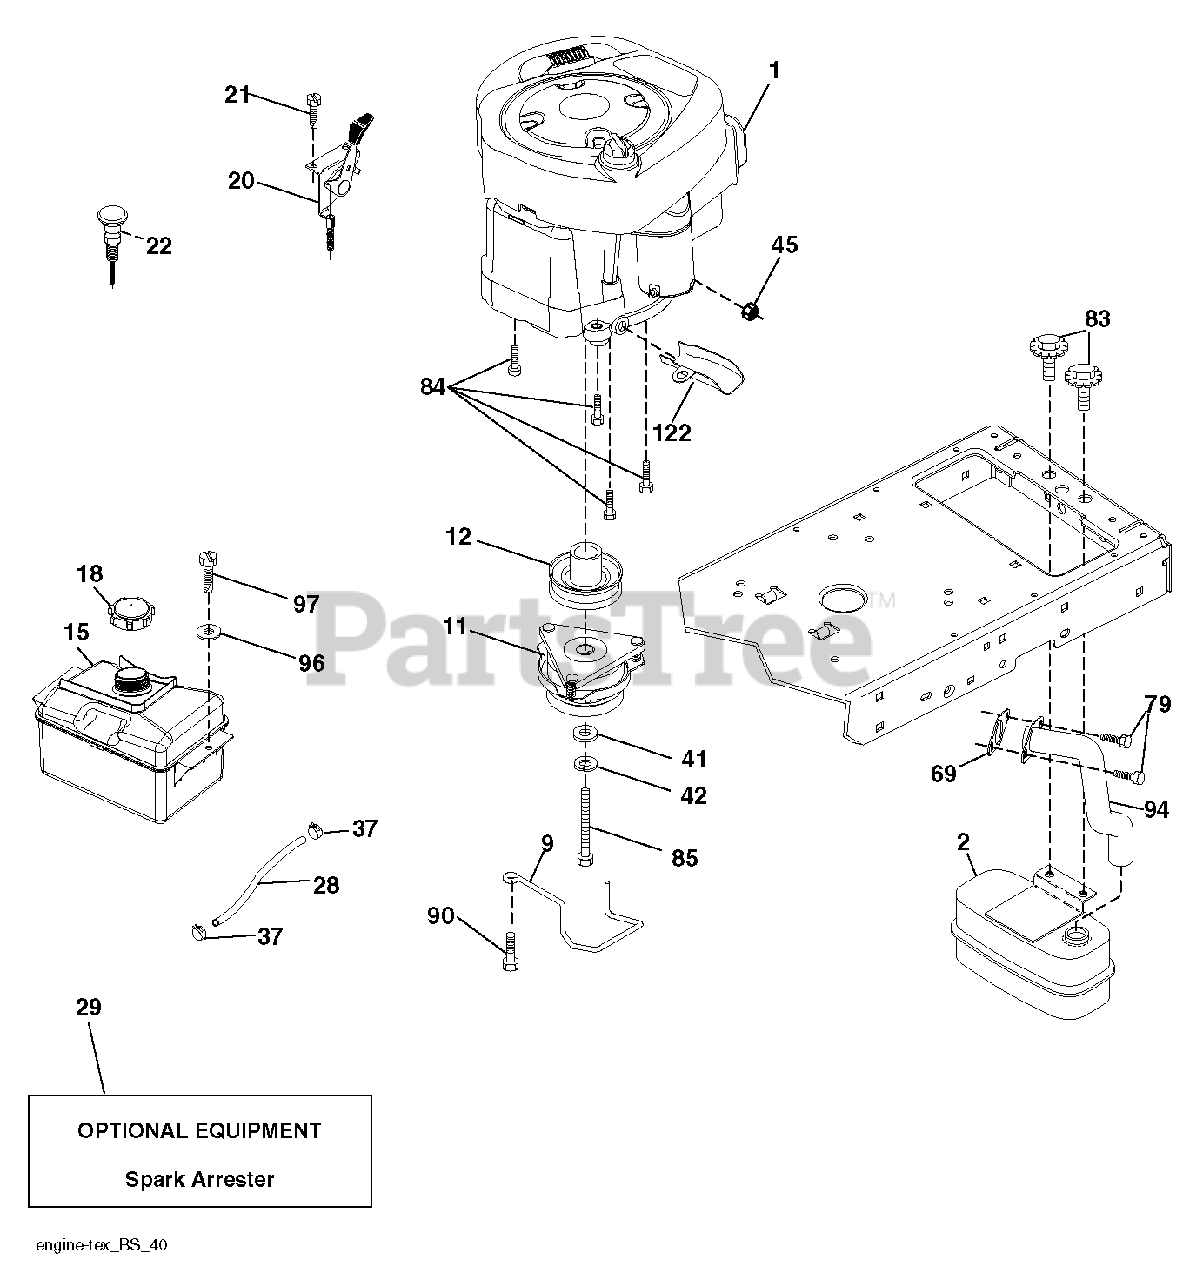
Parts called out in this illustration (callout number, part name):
2	MUFFLER.SINGLE.CYL.KOHL/B&S
9	KEEPER.BELT.ENGINE.4.2
11	CLUTCH
12	PULLEY.ENGINE.TUFFTORQ
18	CAP ASM.FUEL.2.25"FR.
20	CONTROL.TH/CK.COBRA.KO
21	SCREW.#10 X 0.750.BOS THREAD
28	LINE.FUEL.20
29	ARRESTER SPARK (OPTIONAL)
37	HOSE CLAMP
42	LOCKWASHER
45	NUT
69	REPL BY 532 27 22-93
79	SCREW.SOCKET HD.5/16-1
83	BOLT, 5/16-18 X 1 3/4
84	SCREW.3/8-16
85	BOLT HEX 7/16-20X4-1/4"
90	SCREW 3/8-16X1
94	EXHAUST.TUBE.B&S.
97	SCREW HEXWSHR 1/4-20X3/4
122	EXTENSION DRAIN OIL
